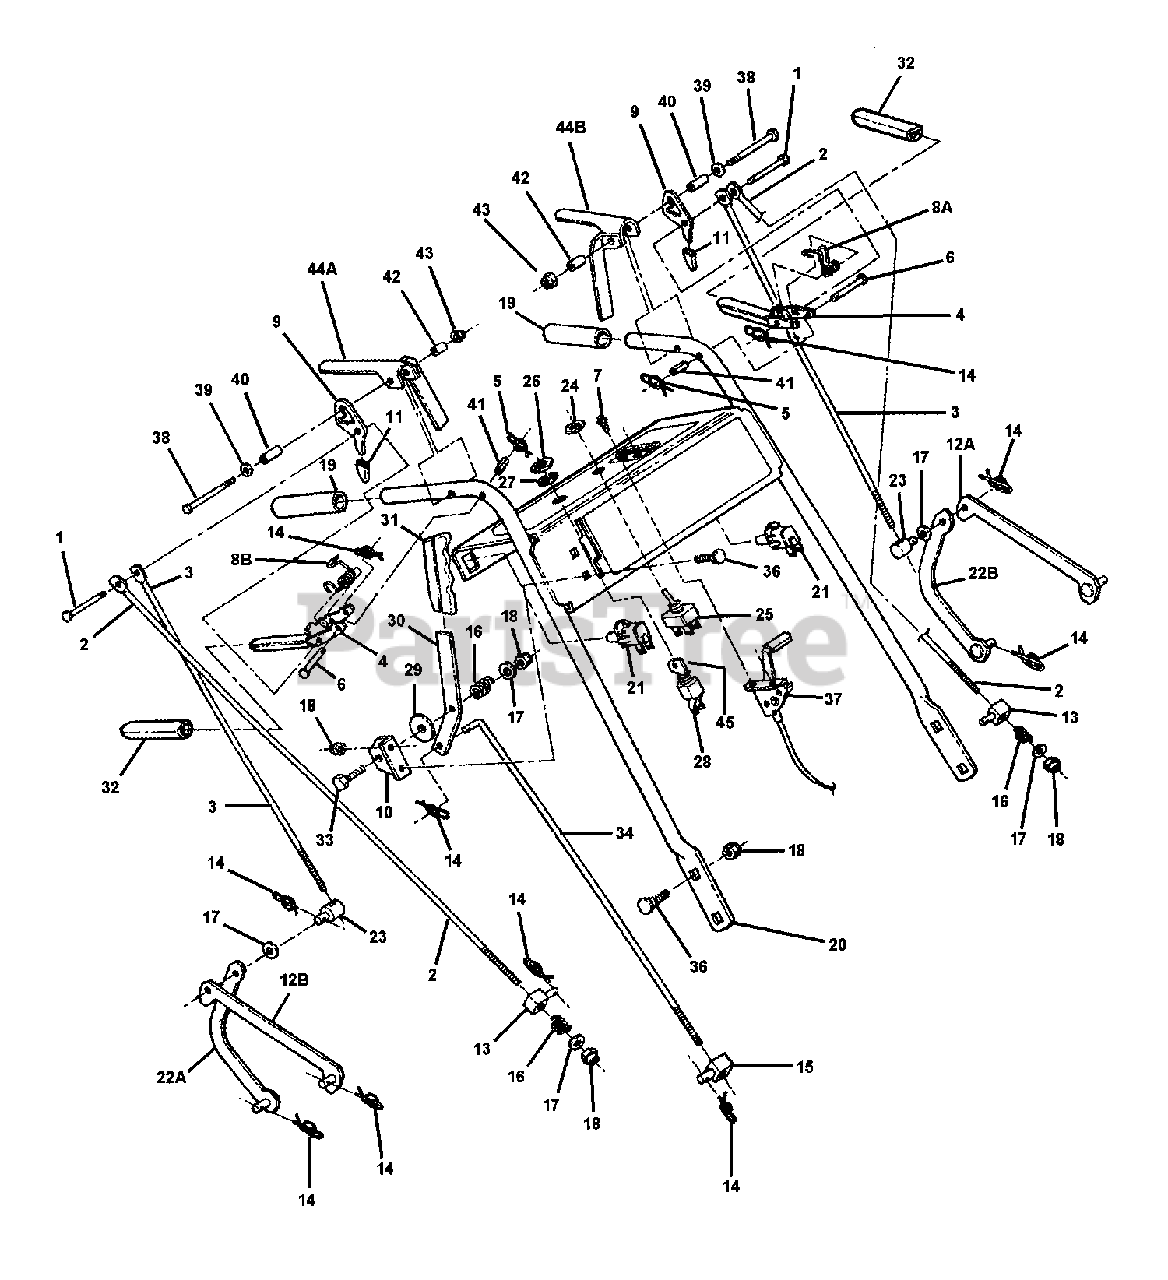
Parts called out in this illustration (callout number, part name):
1	CLEVIS PIN
2	ROD, Brake (3/8-16 thread)
3	ROD, Traction (3/8-16 thread)
4	WELDMENT, Drive Lever (Pistol Grip)
5	COTTER PIN, 5/16 Self Lock
6	CLEVIS PIN, 3/16 x 1-3/4"
7	SCREW, #10-24 x 1/2" Hex Washer Self-Tap
8A	SPRING, Torsion, LH, Drive Lever
8B	SPRING, Torsion, RH, Drive Lever
9	LATCH, Express
10	BRACKET, Shift Handle
11	GRIP, Latch
12A	WELDMENT, Traction Link, Upper LH
12B	WELDMENT, Traction Link, Upper RH
13	SWIVEL, Brake Link- PM
14	COTTER PIN, 1/2" Self-Locking
15	SWIVEL, Brake Link- PM
16	SPRING, Friction Pack
17	WASHER, 3/8" SAE Flat
18	NUT, 3/8-16 HEX NYLON LOCK
19	GRIP, Vinyl .937 x 4-1/2"
20	WELDMENT, Pistol Grip Handle
21	SWITCH, Seat (Normally Closed)
22A	WELDMENT, Traction Link, Lower, RH
22B	WELDMENT, Traction Link, Lower, LH
23	SWIVEL, 3/8-16 Internal Thread
24	NUT, 1/2-27 Hex (Special)
25	SWITCH, Toggle (Indak H671A)
26	NUT, 5/8-32 Hex (Ignition Switch)
27	WASHER, 5/8" Internal Tooth Lock
28	SWITCH, Ignition, 2-Pole, Recoil Start
29	WASHER, Nylon (Wear Spacer)
30	LEVER, Shift
31	GRIP, Flat Bar (Black)
32	GRIP, 3/4 ID x 4" Textured
33	SCREW, 3/8-16 x 1-1/2" Hex Head Cap, GR 5
34	SHIFT ROD, Express (3/8-16 thread)
35	WIRING HARNESS, Pistol Grip
36	BOLT, 3/8-16 x 1" Square Neck Carriage, GR 5
37	CONTROL, Throttle, 42/.88 (Kawasaki)
38	BOLT, 1/4-20 X 3", GD5
39	WASHER, 1/4" Flat
40	SPACER, Brake (Outer)
41	ROLL PIN, 5/16"
42	SPACER, Brake
43	NUT, 1/4-20 HEX NYLON LOCK
44A	GRIP, Pistol OPC (RH) (Weldment)
44B	GRIP, Pistol OPC (LH) (Weldment)
45	KEY, Ignition (Pair)
